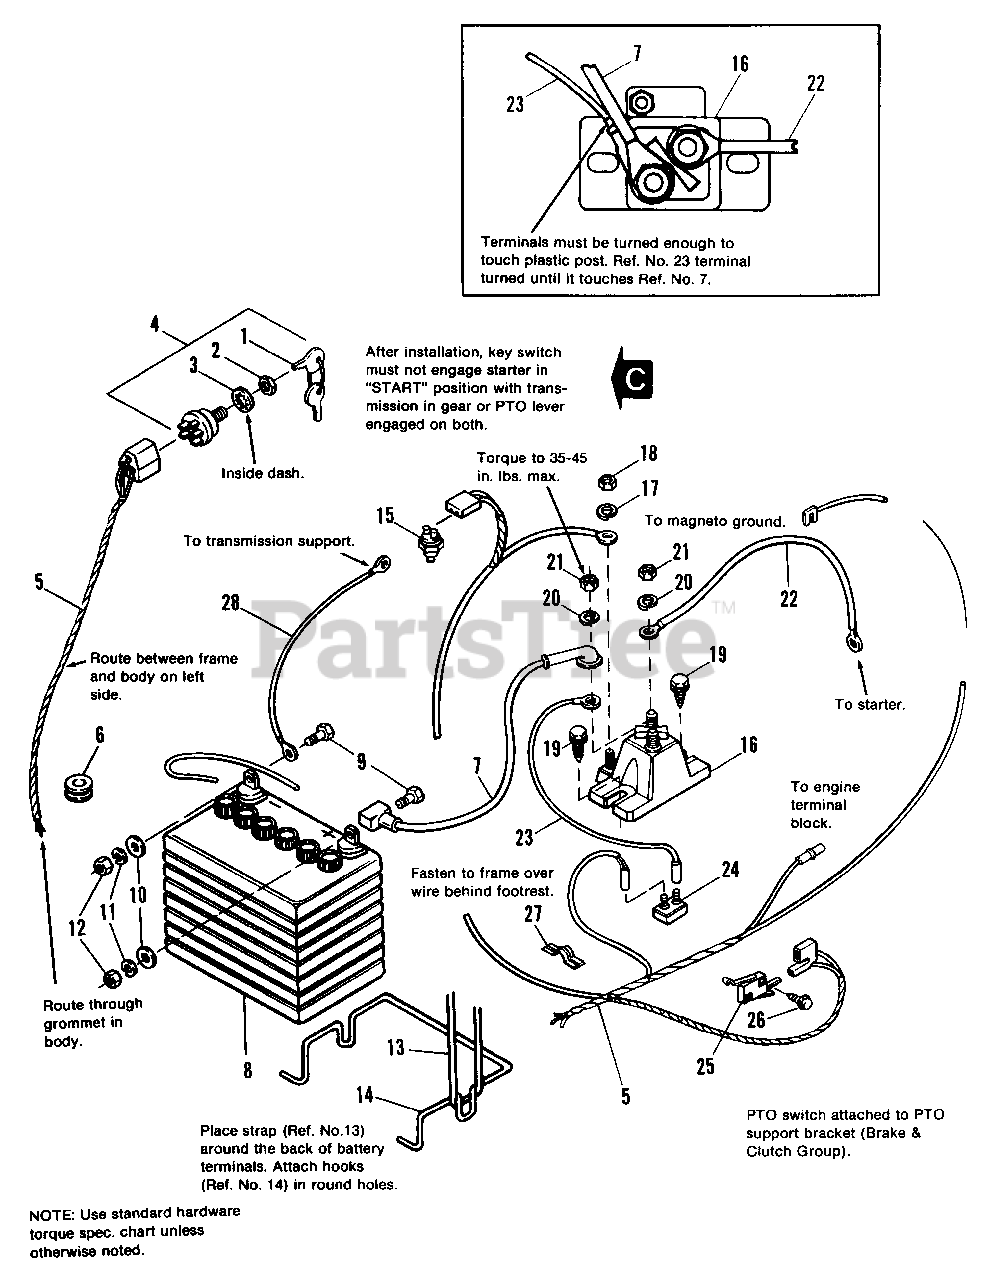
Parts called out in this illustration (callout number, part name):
2	NUT
3	LOCKWASHER, Internal Tooth, 5/8
4	SWITCH, Key (Incl. Ref. Nos. 1, 2 & 3)
5	HARNESS ASSY.
7	CABLE ASSY. (Batt. to Solenoid)
8	BATTERY, 12 Volt
9	CAPSCREW, Hex, 1/4-20 x 3/4
10	WASHER, Plain, 1/4
11	LOCKWASHER, 1/4
12	NUT, Hex, 1/4-20
13	STRAP, Battery
14	BRACE, Battery
15	SWITCH, Transmission Interlock
16	SOLENOID
17	LOCKWASHER, #10
18	NUT, Hex, Machine, #10-32
19	SCREW, Hex, Taptite, 1/4-20 x 3/4
20	LOCKWASHER, 5/16
21	LOCKNUT, Hex, 5/16-18
22	CABLE ASSY. (Solenoid to Starter)
24	BREAKER, Circuit
25	SWITCH, P.T.O. Interlock
26	SCREW, Hex, Taptite, #50-40 x 3/4
27	CLIP, Wire
28	CABLE (Battery to Ground)
